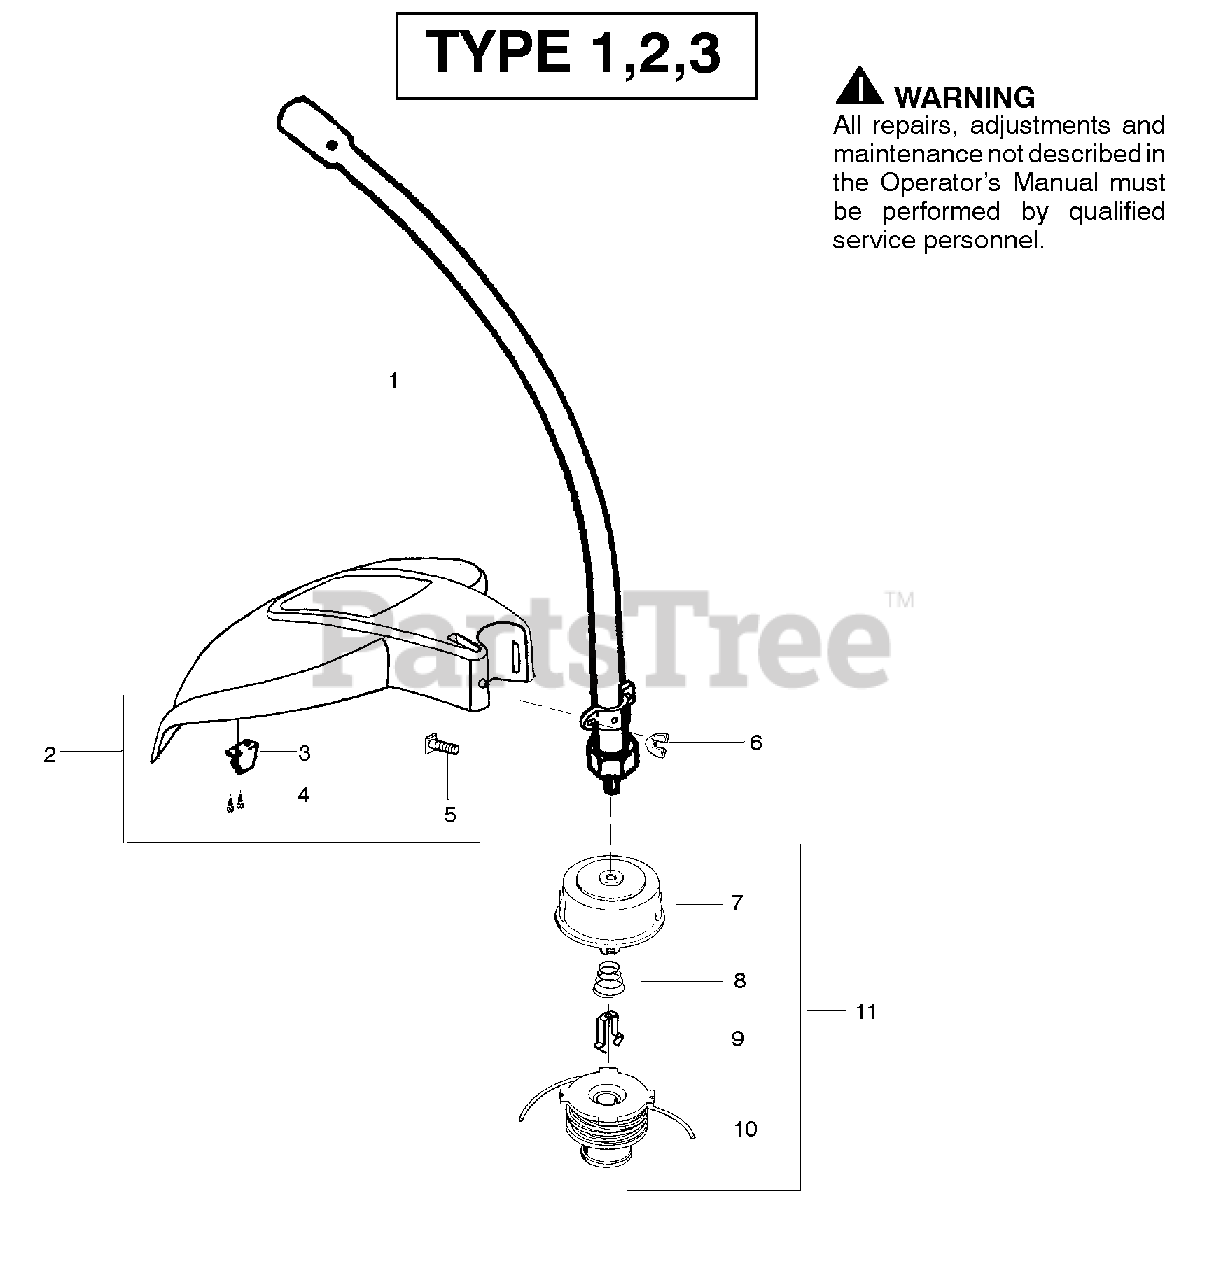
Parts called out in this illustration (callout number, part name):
1	Kit-Lower Shaft Assy.
2	Kit-Shield Assy.
6	Wingnut
7	Assy-Hub/Arbor
8	Spring-Return
9	Retainer-Spool
10	Accy-Wound Spool
11	Accy-Cutting Head
